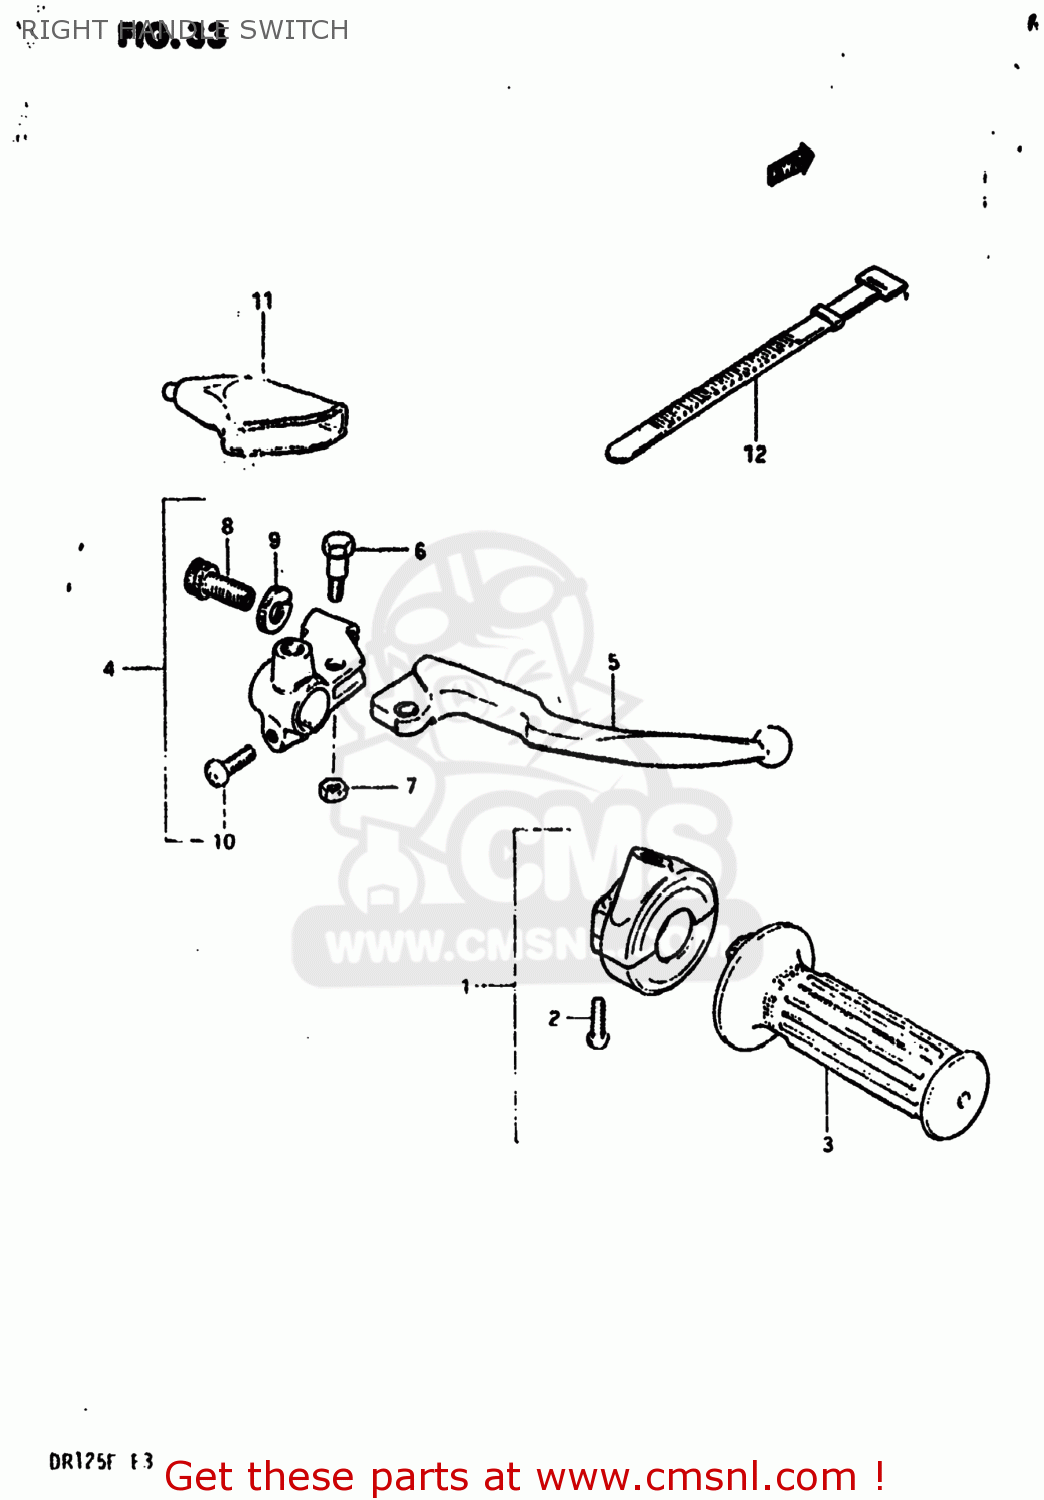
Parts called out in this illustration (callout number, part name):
1	CASE ASSY,THROTTLE
2	SCREW 5X20
3	GRIP,THROTTLE
4	LEVER ASSEMBLY,BRAKE
5	LEVER,BRAKE
6	BOLT,LEVER
7	NUT 6MM
8	ADJUSTER,CABLE
9	NUT,CABLE ADJUSTER
10	SCREW
11	COVER,CLUTCH LEVER
12	CLAMP(L:120)
